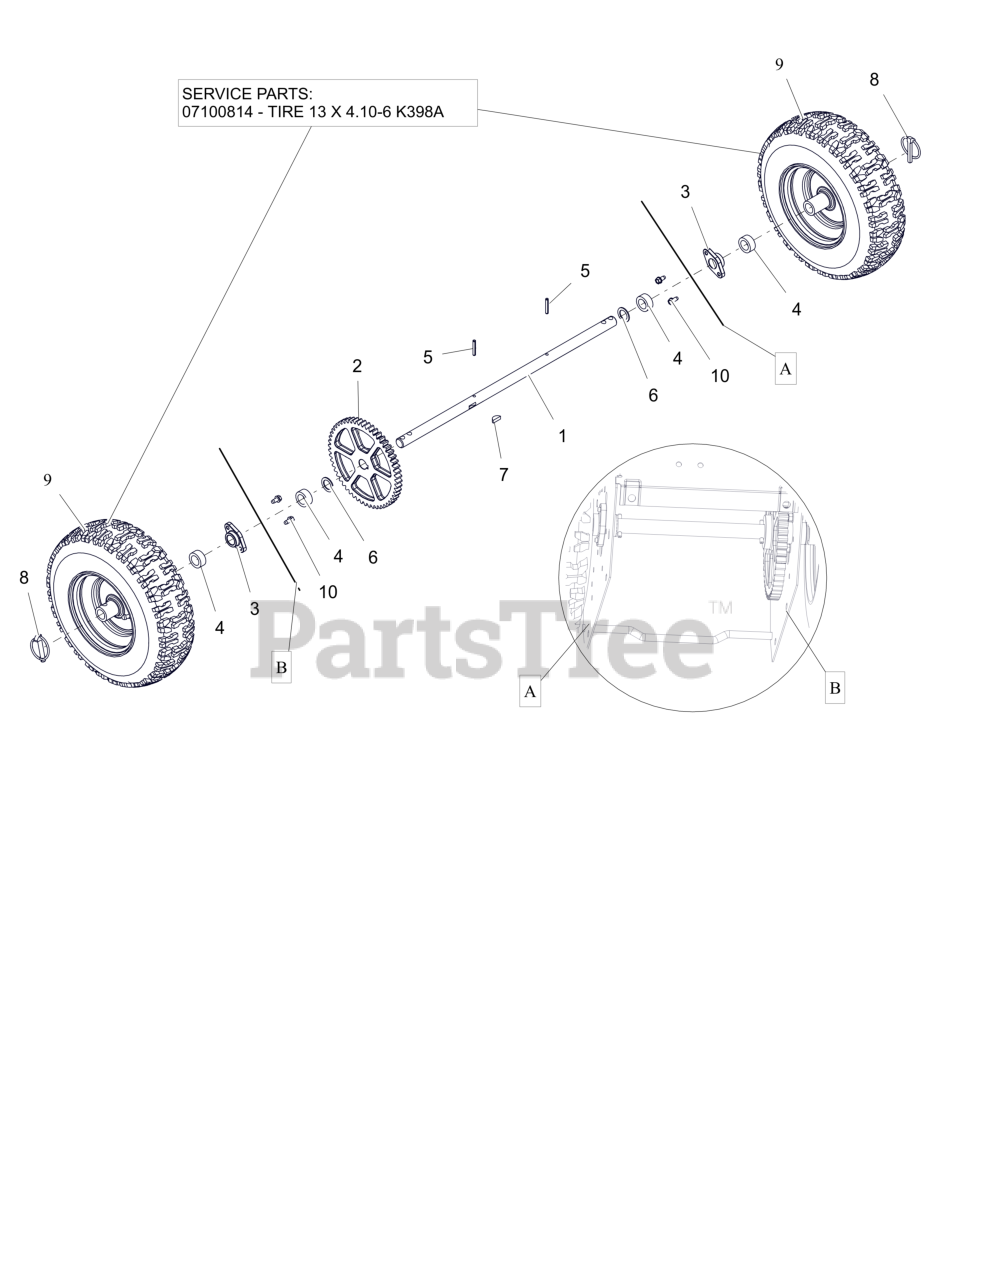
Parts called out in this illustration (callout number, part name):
1	AXLE, COMPACT
2	SPUR GEAR, 54T .75ID X 6.75PD
3	BSHG .75X1.125X.65
4	BSHG-SLV .766 X 1.125 X .500
5	PIN-ROLL .188X1.25
6	WSHR, FLT .754X1.125X.062 ZCC
7	KEY-WDRF .25X.750X.313 SAE91
8	PIN-LOK .31X1.75
9	TIRE/WHEEL 13X4.10-6
9	SNOW TIRE, 13(3.5)/4.10-6 K398A POLAR TRAC
9	VALVE STEM ASS'Y
10	SCR-TAP .25-20X.50 HWH ZCC
